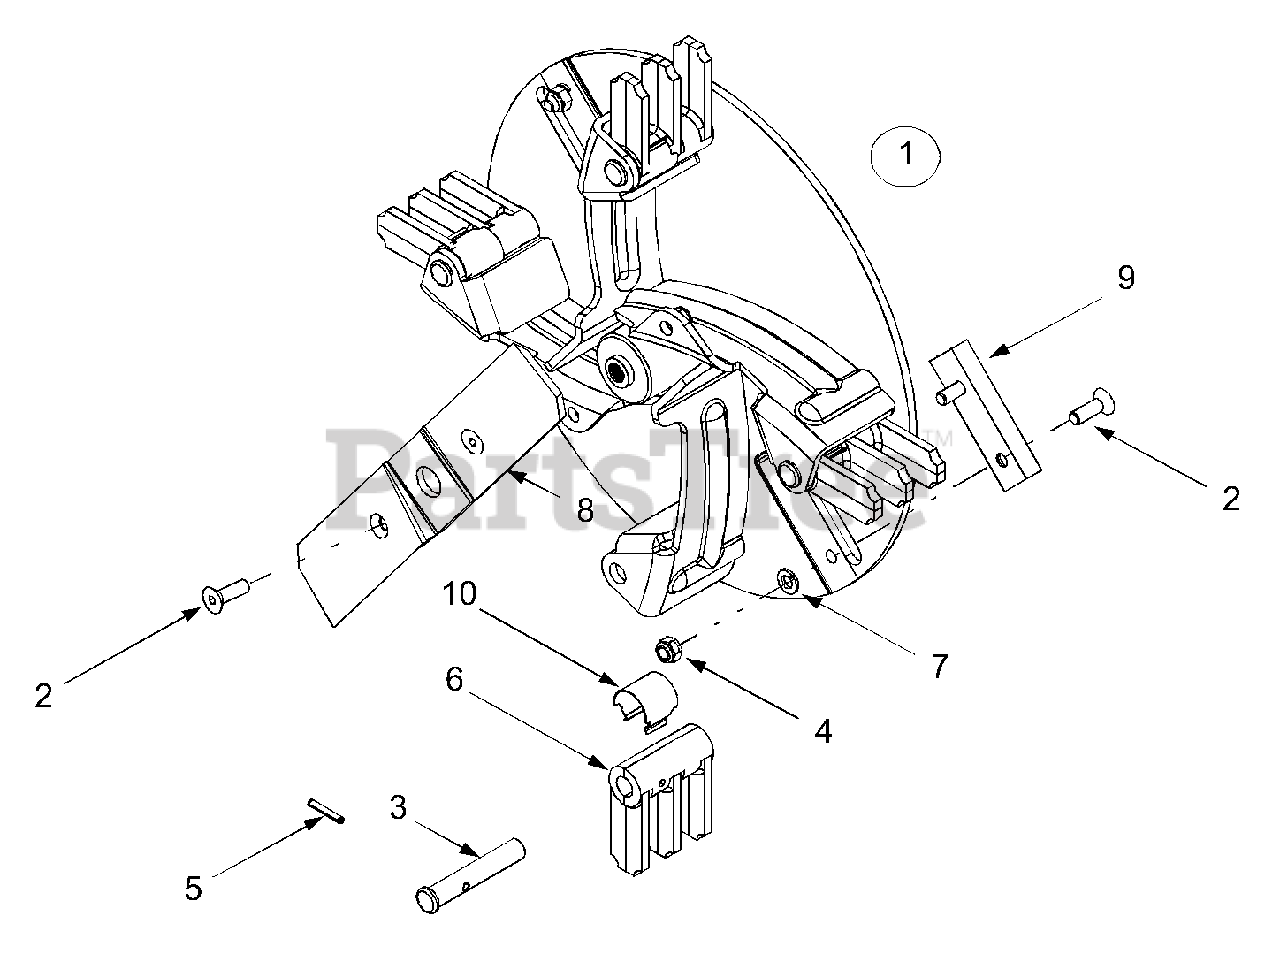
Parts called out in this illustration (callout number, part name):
1	Impeller Assembly Complete
2	Machine Screw, 5/16-24 x 1.0
3	Clevis Pin,.496
4	Hex Lock Nut, 5/16-24
5	Spiral Pin,.156 x 1.0
7	Lock Washer, 5/16
8	Shredder Blade
9	Chipper Blade
10	Retainer Clip
